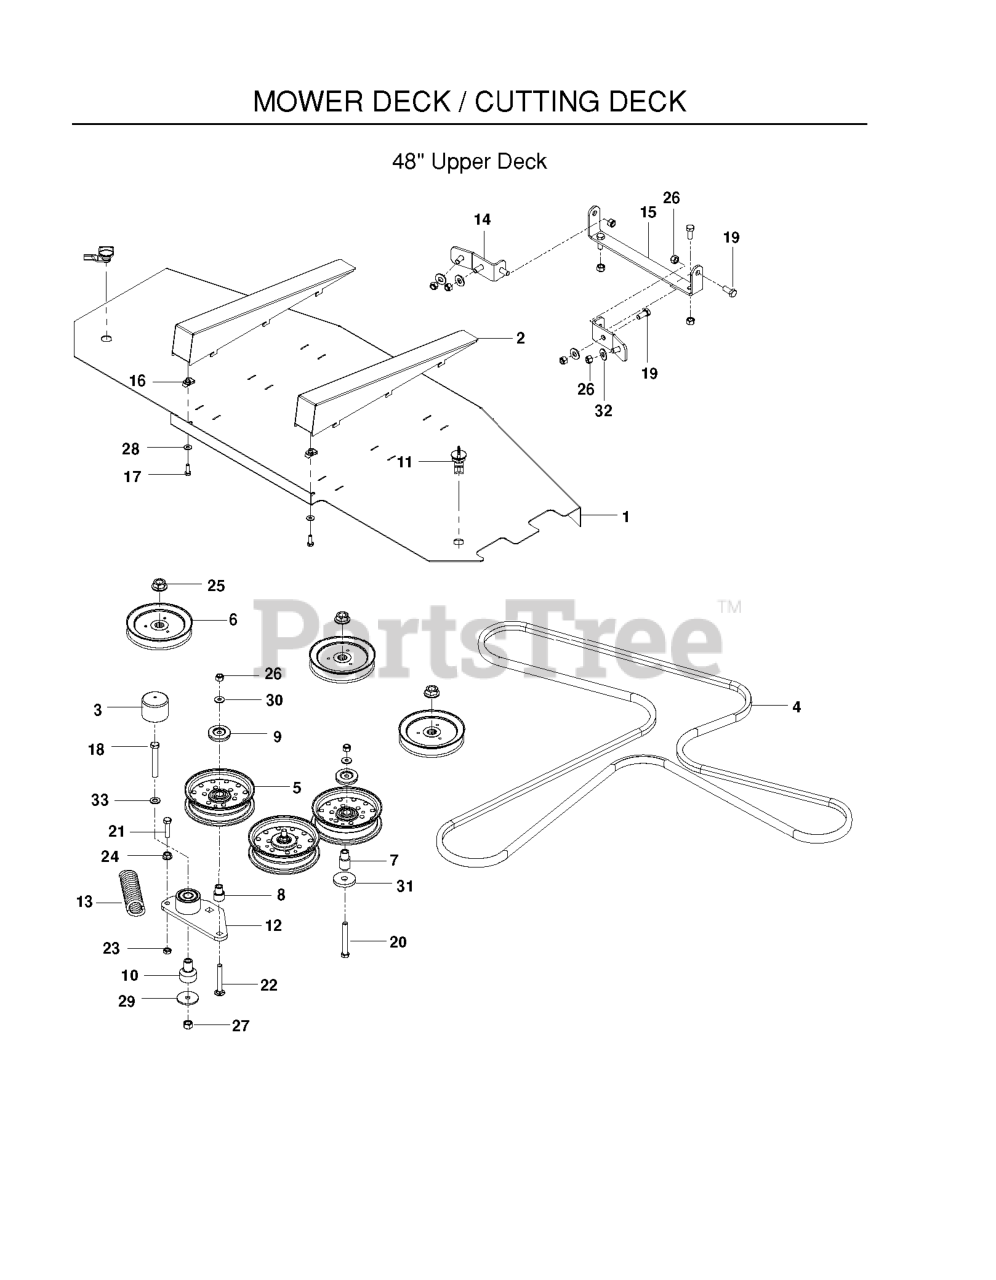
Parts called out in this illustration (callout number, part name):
1	COVER - BELT, 48 PAINTED
2	WEDGE - PAINTED
3	CAP, VINYL
5	PULLEY - 5.25
6	IDLER PULLEY
7	IDLER BUSHING
8	BUSHING, IDLER
9	DUST SHIELD
10	PIVOT, BEARING
11	LATCH, SHORT WING
12	ARM-IDLER W/BRG
14	HINGE, BIN
15	BASE HINGE - PAINTED
16	1/4C - U TYPE RETAINER
17	HCS 1/4C X 3/4 HCS
18	HCS 1/2C X 3 1/4
19	HCS 3/8-16 X 7/8 GR 5 ZD
20	HCS 3/8C X 3
21	HCS 3/8-16 X 1-1/2
22	RHSNB 3/8-16 X 2.75
23	NUT 3/8-16 HEX JAM
24	NUT 3/8C WHIZ
25	NUT FLANGE 3/4-16
26	NUT 3/8-16 NYLOC
27	NUT 1/2-13 HEX NYLOC ZD
28	WASHER 1/4 SAE
29	WASHER, SUPPORT
30	WASHER, 3/8 THICK
31	SPINDLE WASHER
32	WASHER 3/8 FLAT
33	CONTACT BELLSPR 1/2
